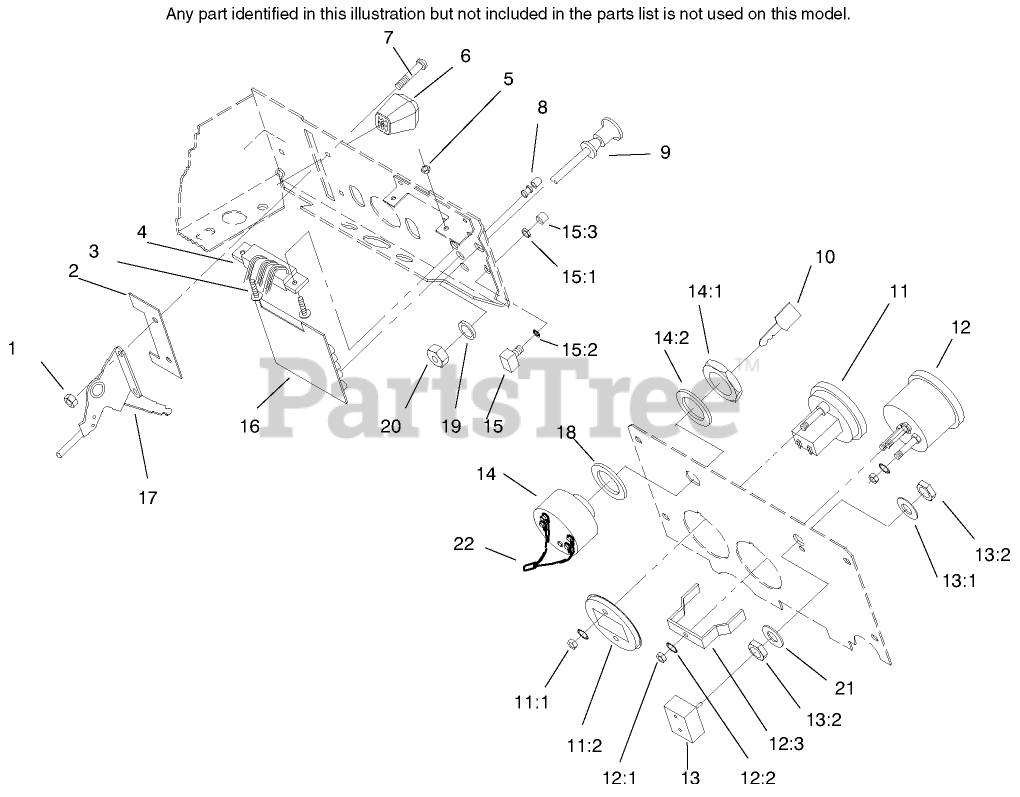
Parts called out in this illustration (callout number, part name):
7	SCREW-PPH
9	CONTROL CHOKE
10	KEY-IGNITION
11:1	NUT-HEX, KEPS
11:2	Retainer
13	SWITCH-LIGHTS
13:1	TAB-WASHER
13:2	*DISC**
14	KEY SWITCH ASM
14:2	Washer-Lock
17	CONTROL-THROTTLE
18	WASHER
19	WASHER-FLAT
20	NUT-HEX PALNUT
21	WASHER
